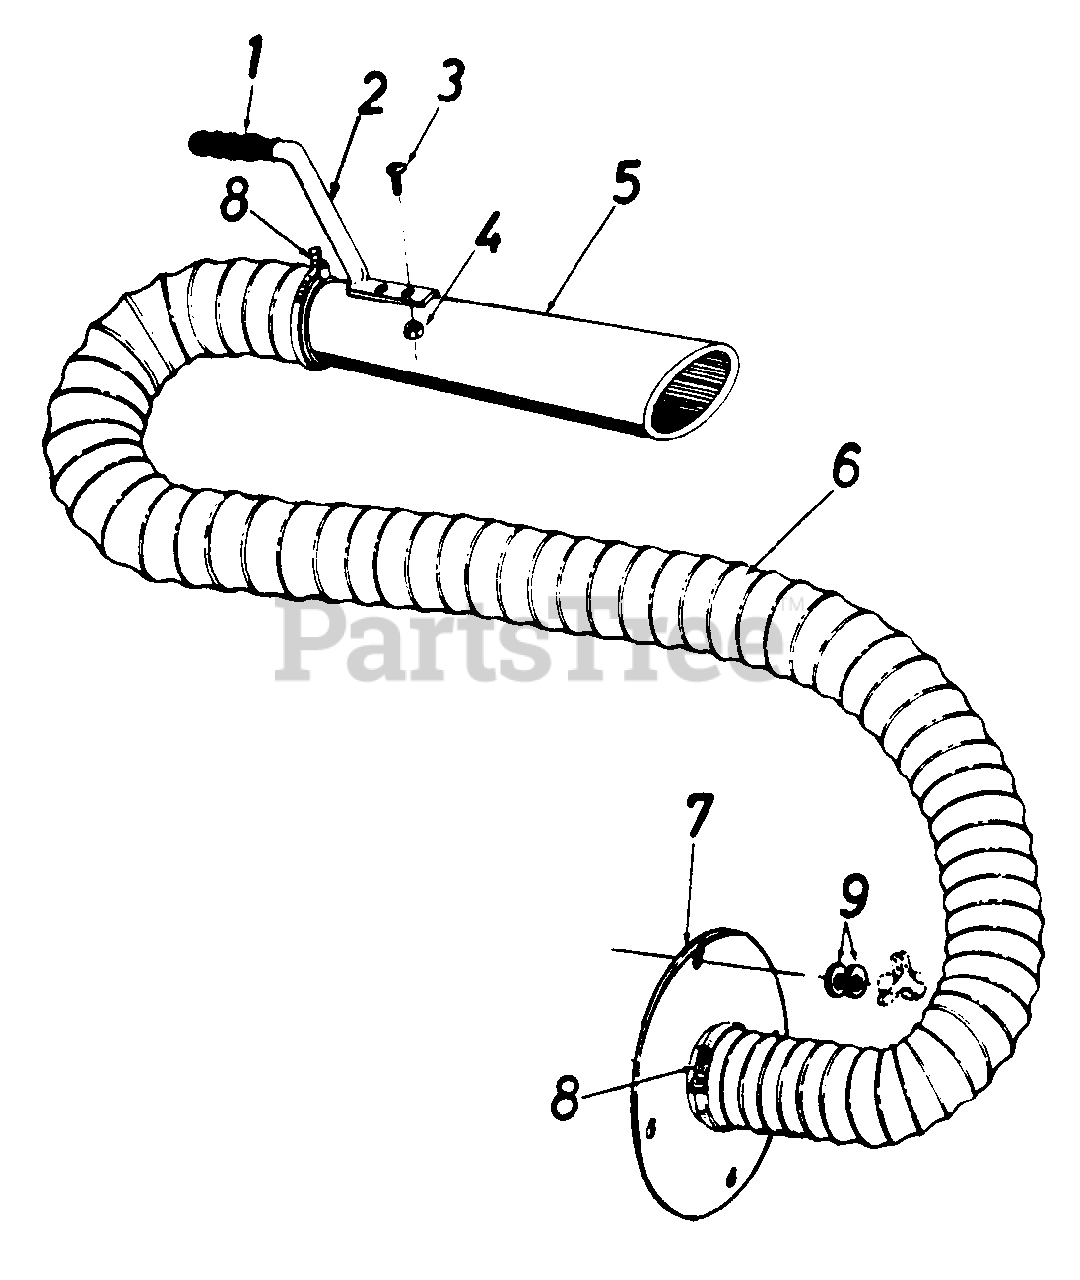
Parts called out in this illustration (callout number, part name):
1	Handle Grip
3	Truss Sems Scr. 10-32 x 1/2" Lg.
4	Hex Nut 10-24 Thd.
5	Hose Nozzle
6	Flexible Hose 4" Dia. x 10' Lg.
9	Flat Washer .34 I.D. x 1.12 O.D.
